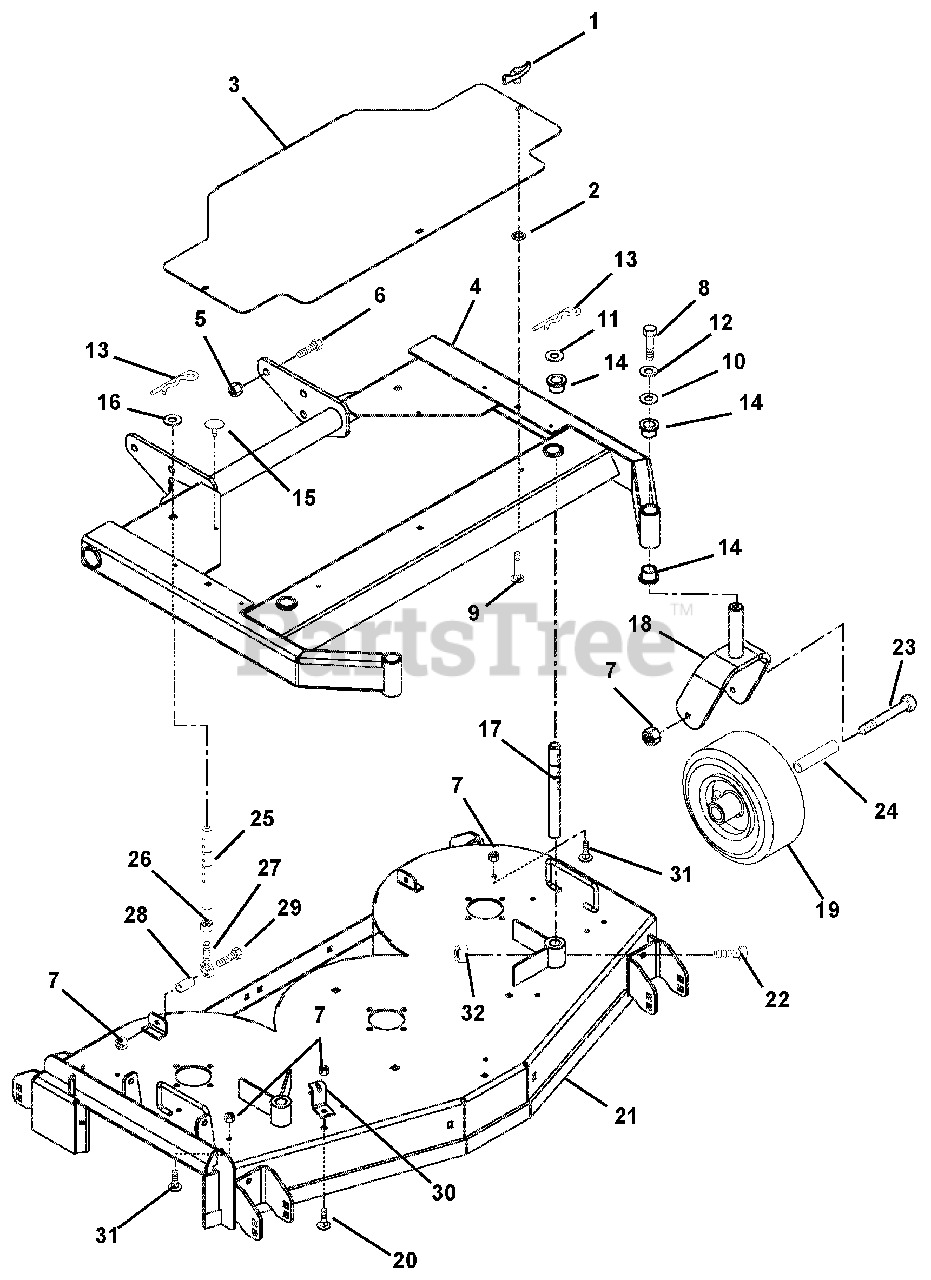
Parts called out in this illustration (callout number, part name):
1	Knob- Wing .312-18
2	Nut-Push .312
3	Cover, Belt Pro Mower
4	Weldment-Mower Frame 48" Floating (107, 108, 116)
5	Nut-Locking-Nylon .625-11
6	Bolt-Hex .62-11 x 1.50
7	Nut-Locking-Top-Flange .38-16
8	Bolt-Hex .38-16 x 1.25 Grade 5
9	Bolt-Round Head Square Neck .31-18 x 1.00
10	Washer-Flat-Steel .38 x 1.50 x .125
11	Washer-Flat-Steel .875 x 1.50 x .120
12	Washer-Locking .38 x .094 Regular
13	Pin-Hair-Internal .17 x .68 x 3.50
14	Bushing-Flange 1.00 x 1.25 x 1.50 x 1.50
15	Bumper Grommet .125 x .25 Dia.
16	Washer-Flat-Steel .688 x 1.75 x .134
17	Rod- Front Height Adjustment
18	Weldment-Caster Fork
19	Wheel 9 x 3.50
20	Bolt-Round Head Square Neck .38-16 x 1.00 Grade 5
21	Kit, 48" Floating Mower Deck with Decals (107, 108, 116)
22	Bolt-Hex .25-20 x 2.25 Grade 8
23	Bolt-Hex .38-16 x 5.50
24	Bearing .625 x .380 x 4.08
25	Rod- Rear Height Adjustment
26	Nut-Jam .375-24
27	Rod End, .38 Right Hand
28	Bushing-Sleeve .377 x .624 x .37
29	Bolt-Hex .38-16 x 1.50 Grade 5
30	Anchor, Spring
31	Bolt-Round Head Square Neck .38-16 x .75 Grade 5
32	Nut-Locking-Top-Flange .25-20
